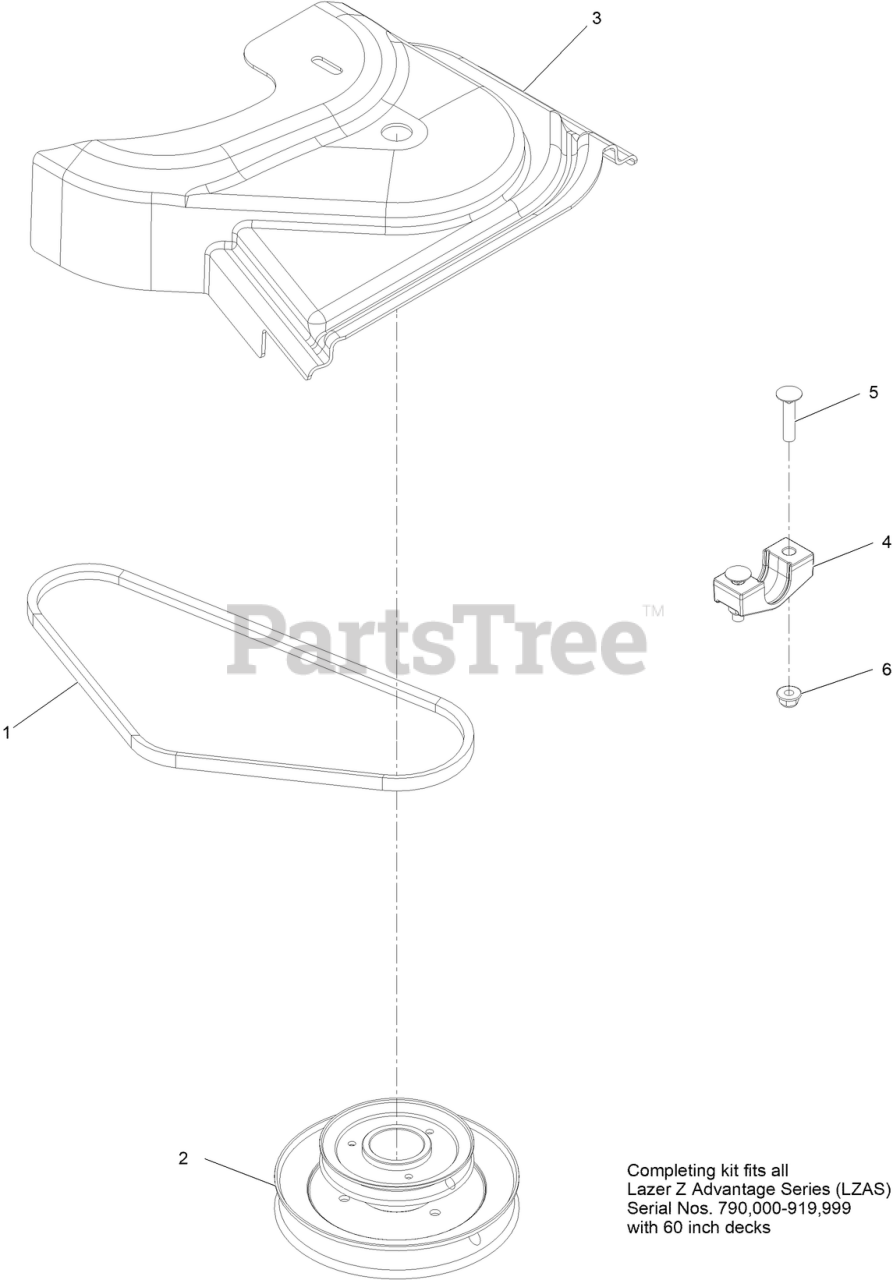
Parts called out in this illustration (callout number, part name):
2	JACKSHAFT,UV DRIVE 604
3	COVER,BELT UV 60
4	SUPPORT-BEARING CROSS SHAFT
5	SCREW-CARR
6	NUT-HF, NI
